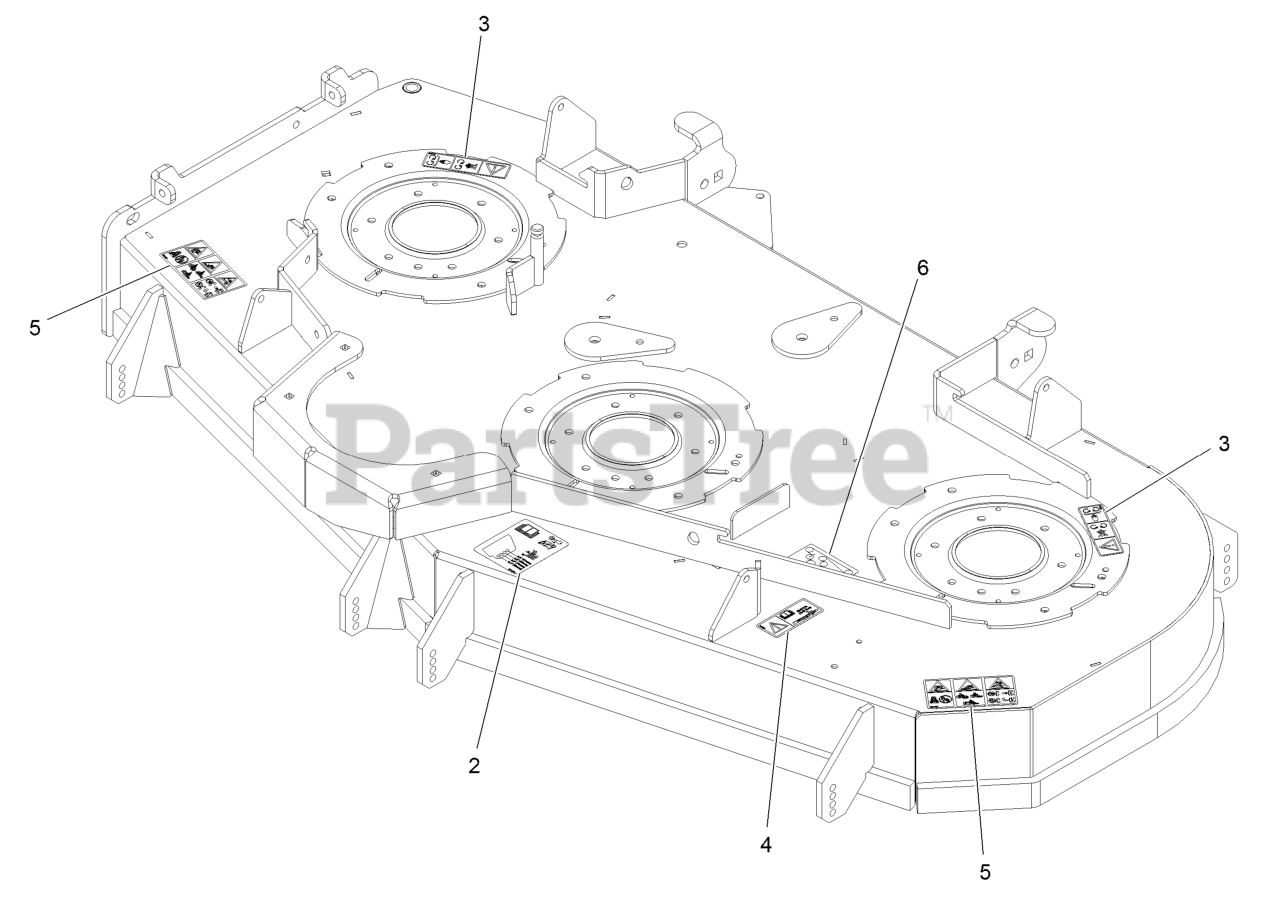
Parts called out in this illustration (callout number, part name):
2	Decal-Roller, Anti-Scalp
3	Decal-Cover, Missing
4	Decal-Bolt Torque
5	Decal-Danger Thrown Objects
6	Decal-Belt 60 Side
